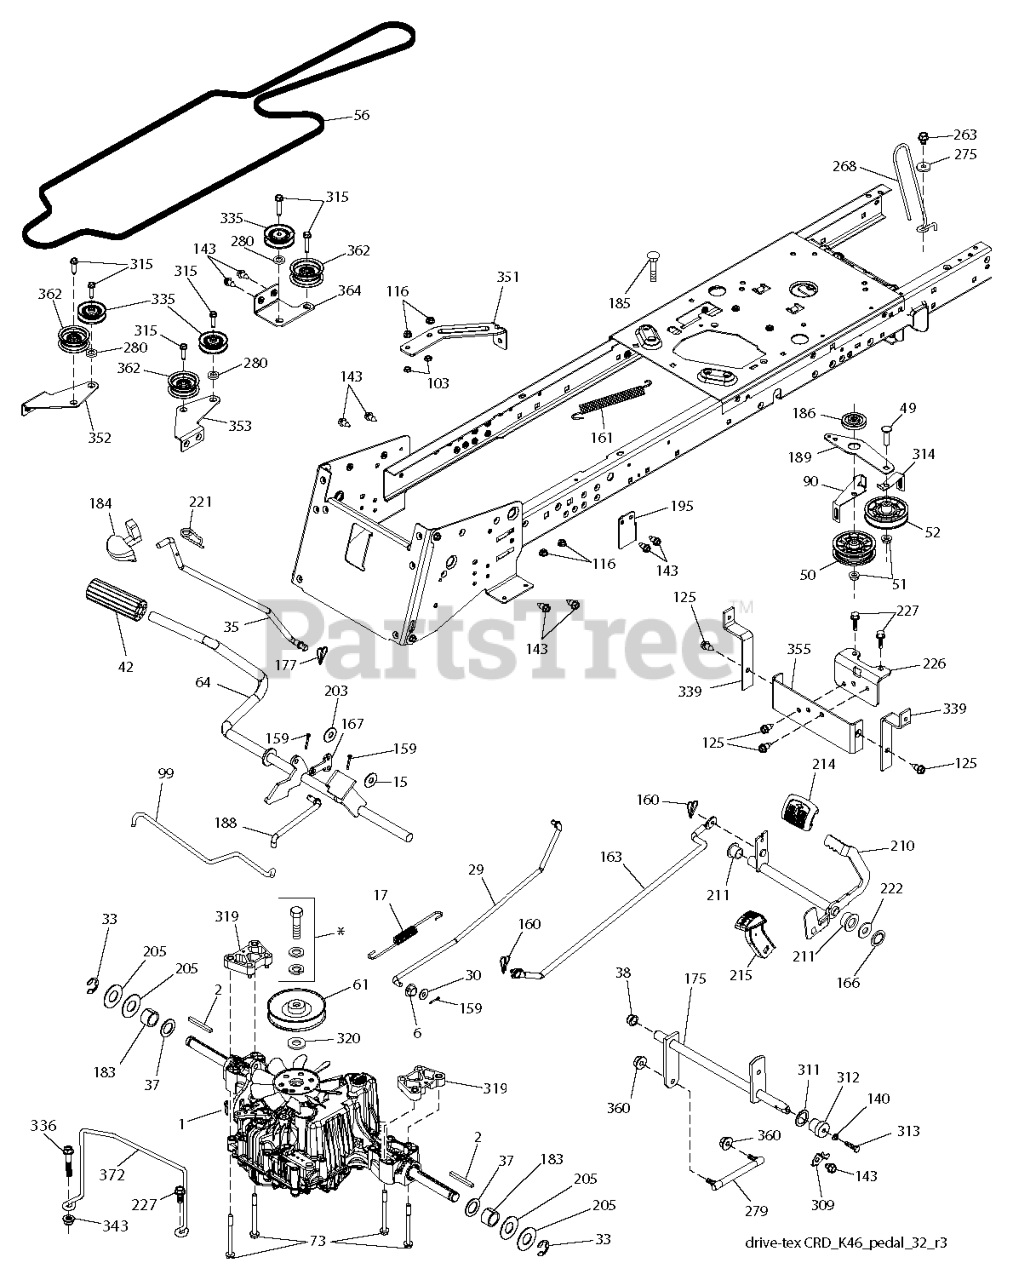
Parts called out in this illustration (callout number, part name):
2	SQUARE KEY
6	BUSHING.SNAP.NYL.BLK.
15	WASHER PLAIN WASHER 3/8 X 0.08
17	SPRING
29	ROD
37	WASHER.HARDENED
38	NYLINER SNAP 5/8" ID
42	PEDAL COVER
50	IDLER.FLAT.910.OFFSET
51	NUT LOCK FLG 3/8-16 UNC
52	IDLER.V-GROOVE.910.OFFSET
61	PULLEY
64	SHAFT.ASM.PEDAL.BRK.CNTR
73	BOLT.HEX.FLNG.5/16-18X3.75
90	KEEPER KEEPER BELT CLUTCHING T
99	ROD ROD BYPASS CRD TEX GEN 2
125	SCREW
140	WASHER SPRING LOCK WASHER WITH
160	GSPW Retainers
161	SPRING, RETURN LT
163	ROD
166	NUT.PUSH.625
167	LATCH.BRAKE.SPRING
175	SHAFT SUBASM.SHAFT.CROSS.SHIFT
177	PIN COTTER;LOCKING;BOWTIE;1IN
183	SPACER AXLE
184	HANDLE.PARKNG BRK.PRED.LT.428
186	SPACER.RETAINER
188	LINK.CLUTCH.GROUND DRIVE.LONG
189	BELLCRANK BELLCRANK GROUNDDRI
195	BRACKET.ROD.BRAKE
203	WASHER 11/32 X 11/16 X 14 GA T
210	ROCKER.ASM.PEDAL.CONTR
211	BEARING.NYLON
214	PEDAL.FORWARD.PAD.TEX
215	PEDAL.COVER.REVERSE.CRD.X428BK
221	RETAINER.SPRING.CLIP.H
222	WASHER 21/32 X 1-1/4 X 10 GA.
226	BRACKET.MOUNT.TORQUE.K46.TLT
263	SCREW, 3/8-16X3/4
309	PLATE FASTENING LT
311	WASHER NYL
312	HUB.TAPERED.ROUND.CRD
314	RETAINER KEEPER BELT
315	BOLT.5/16-18X1.25
319	SPACER SPACER TRANSAXLE TEX C
320	WASHER.SPACER.MANDREL
335	PULLEY.V-IDLER.
336	Bolts
339	STRAP STRAP TORQUE K46 CRD TE
343	NUT HEXAGON FLANGE 5/16-18 ST
351	BRACKET BRACKET DECK SWAY
352	BRACKET BRACKET.IDLER
353	BRACKET
355	STRAP STRAP TORQUE K46 CRD TEX
360	NUT NUT HEX CENTERLOCK 5/16-24
362	IDLER.FLAT.2.25.INCH
364	BRACKET BRACKET IDLER CRD TEX
372	KEEPER.BELT.CRD2.K46.2.BOLT.
